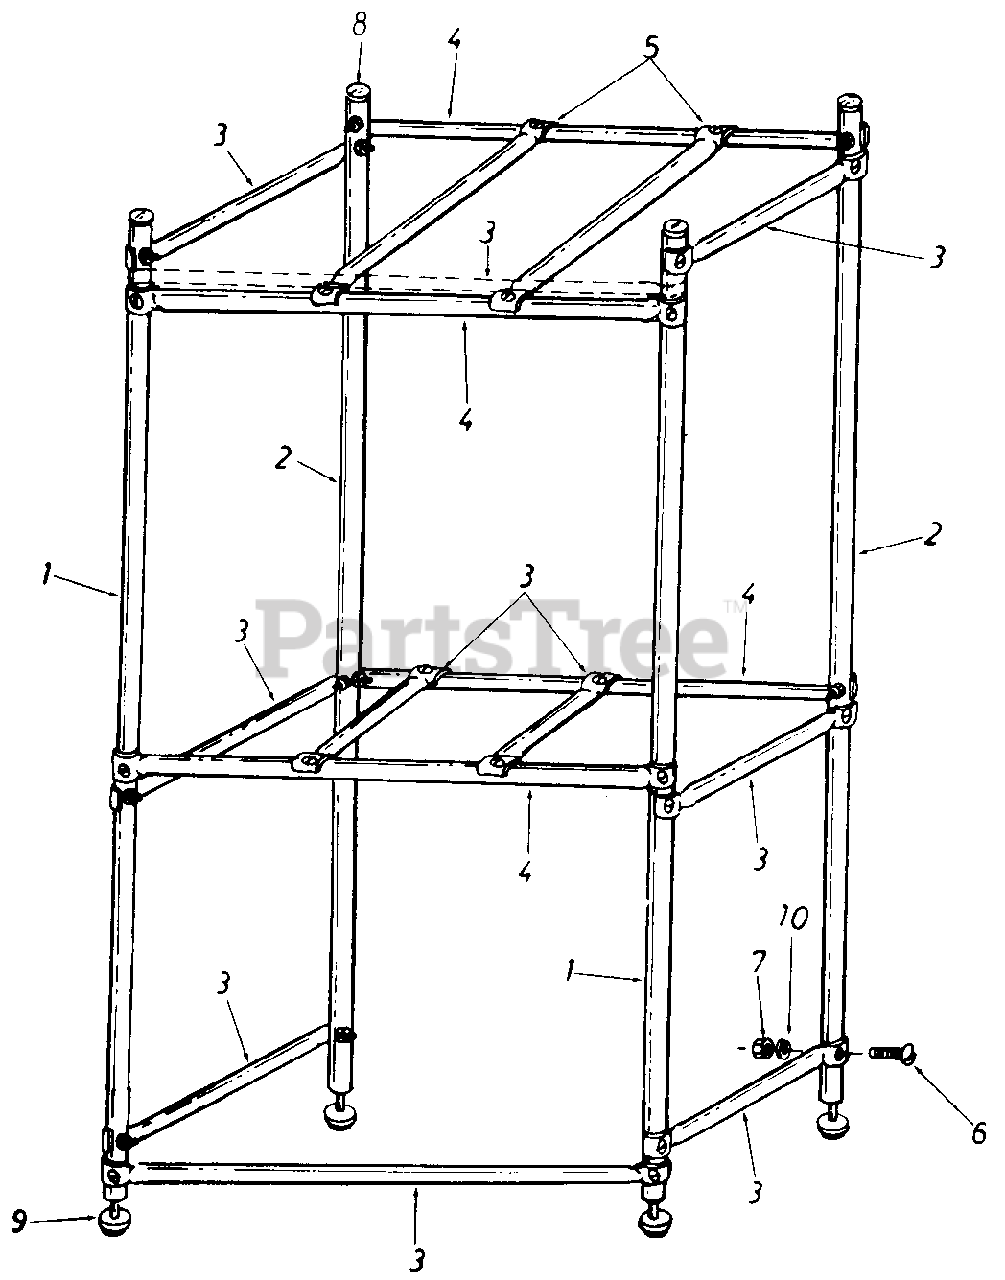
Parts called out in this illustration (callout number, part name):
3	Cross Brace w/o Center Holes 31" Lg. (Tubing Parts)
6	Truss. Mach. Screw 1/4-20 x 1-1/2" Lg.
7	Hex Nut 1/4-20 Thd.
8	1" Tubing Plug
9	1" Swivel Glide
10	Lock Washer 1/4" I.D
